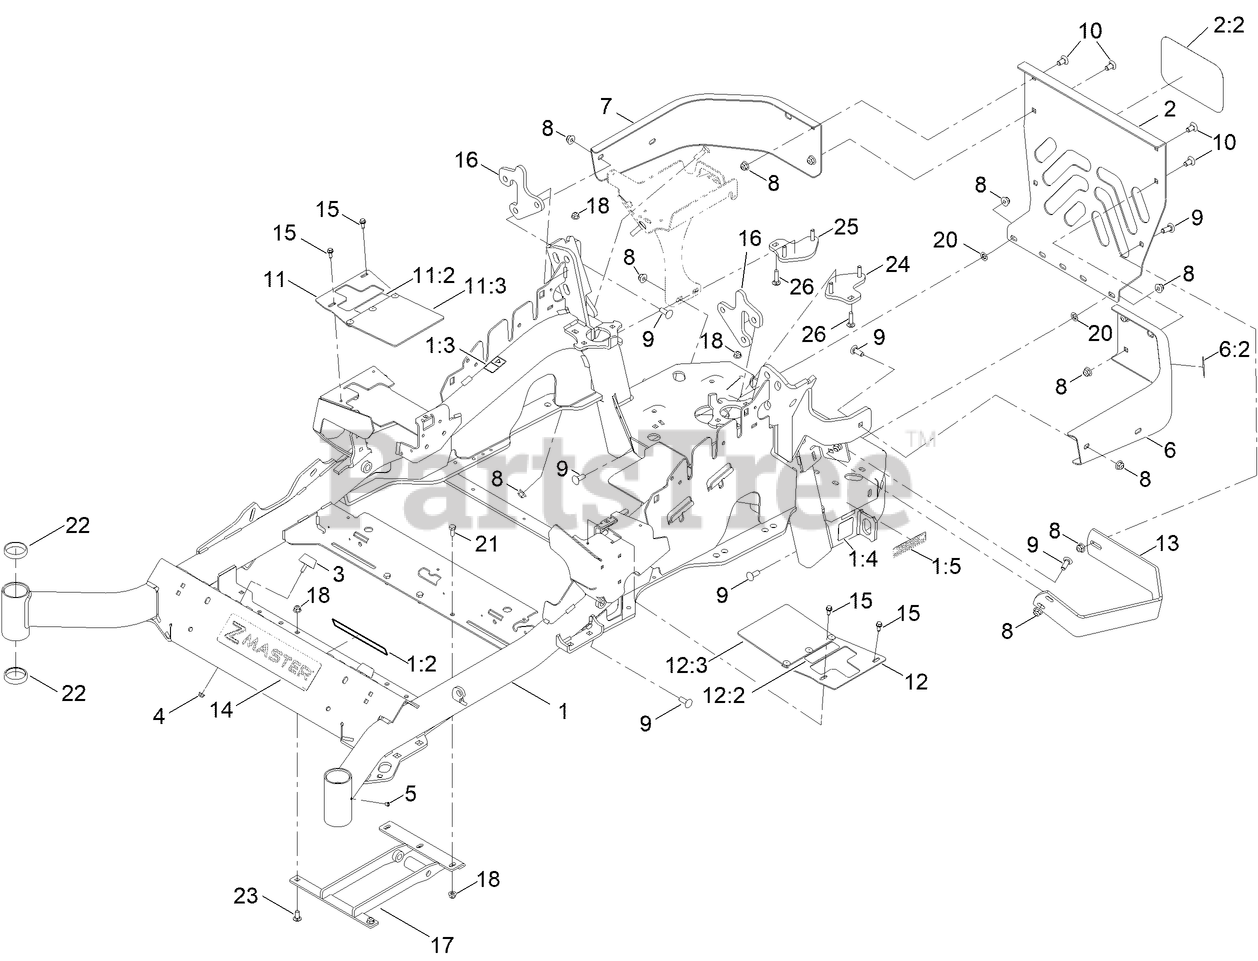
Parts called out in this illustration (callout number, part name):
1	MAINFRAME SERVICE ASM - 60
1:2	DECAL-DANGER
1:3	DECAL-WARNING
1:4	DECAL-HAZARD, PINCHED FINGER
1:5	DECAL-ARRESTOR, SPARK
2	REAR GUARD ASM
2:2	DECAL
3	BUMPER
4	NUT-HF
6	LH BUMPER ASM
6:2	DECAL-WARNING
7	BUMPER-RH
8	NUT-HF, NI
9	SCREW-CARR
10	SCREW-CARR
11	RH MOTION CONTROL COVER ASM
11:2	DECAL-CONTROL, MOTION
11:3	FLAP-RUBBER
12	LH MOTION CONTROL COVER ASM
12:2	DECAL-CONTROL, MOTION
12:3	FLAP-RUBBER
13	GUARD-MUFFLER
14	DECAL-CONSOLE
15	SCREW-HWH
16	PLATE-MOUNT, SHOCK
17	MOUNT-LOWER
18	NUT-HF, NI
20	NUT-PUSH
21	SCREW-HH
22	CUP-BEARING
23	SCREW-CARR
24	LH PLATE ASM (W/STUDS)
25	RH PLATE ASM (W/STUDS)
26	SCREW-CARR
